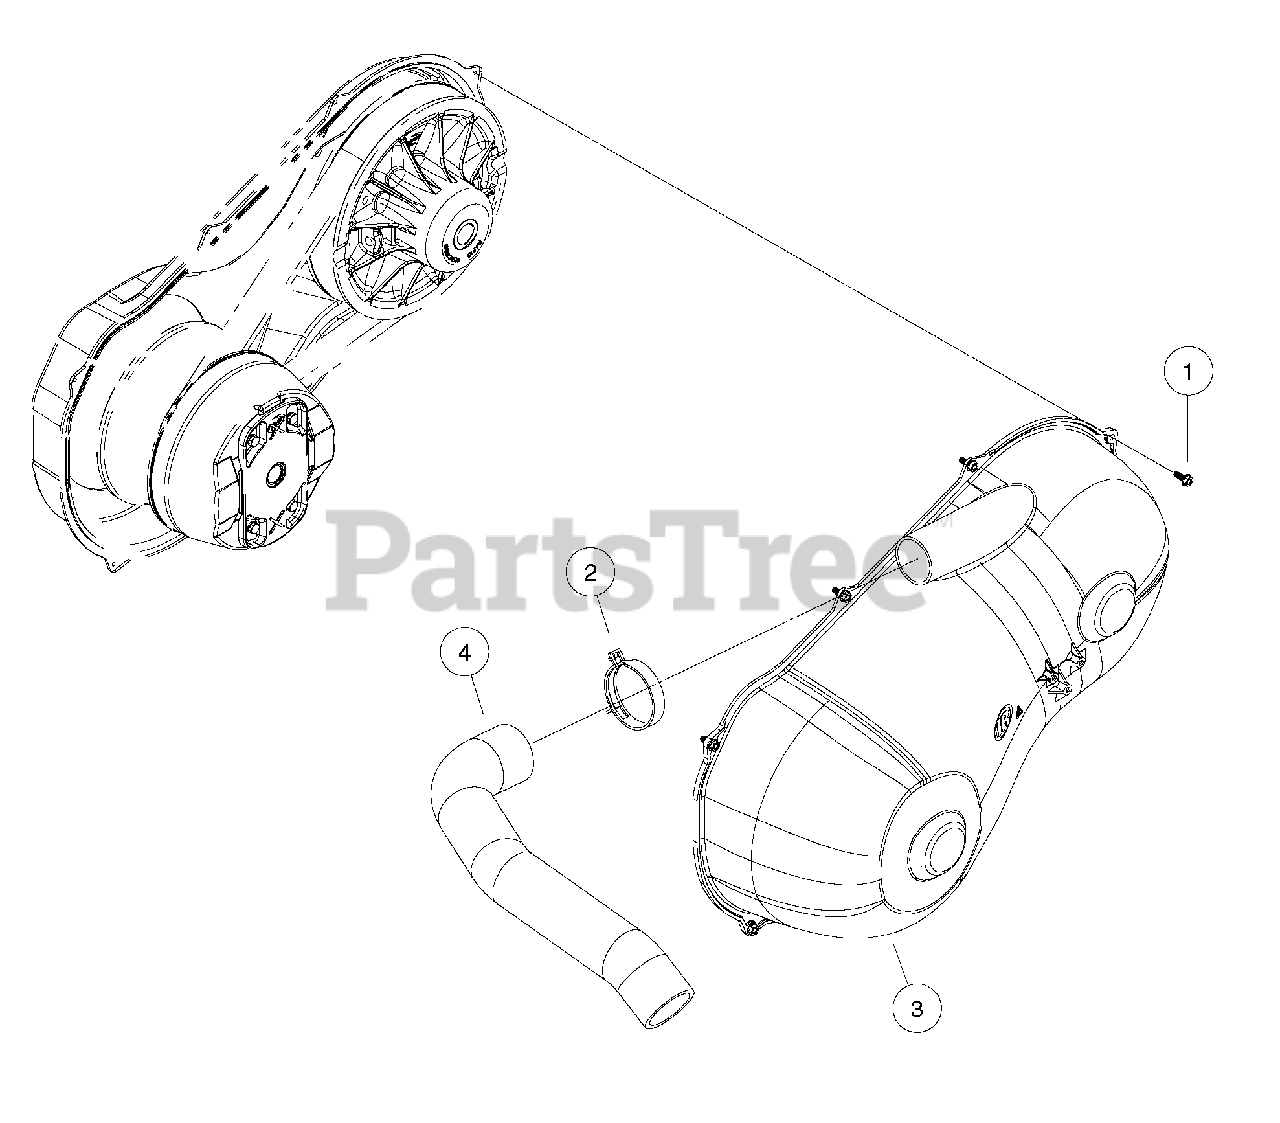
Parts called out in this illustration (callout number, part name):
1	Screw, M6 X 16 Tt Hx Fl Hd
2	Clamp, Hose, Ctb 64mm
3	Cover, Cvt, Open
4	Hose, Outlet, Cvt
